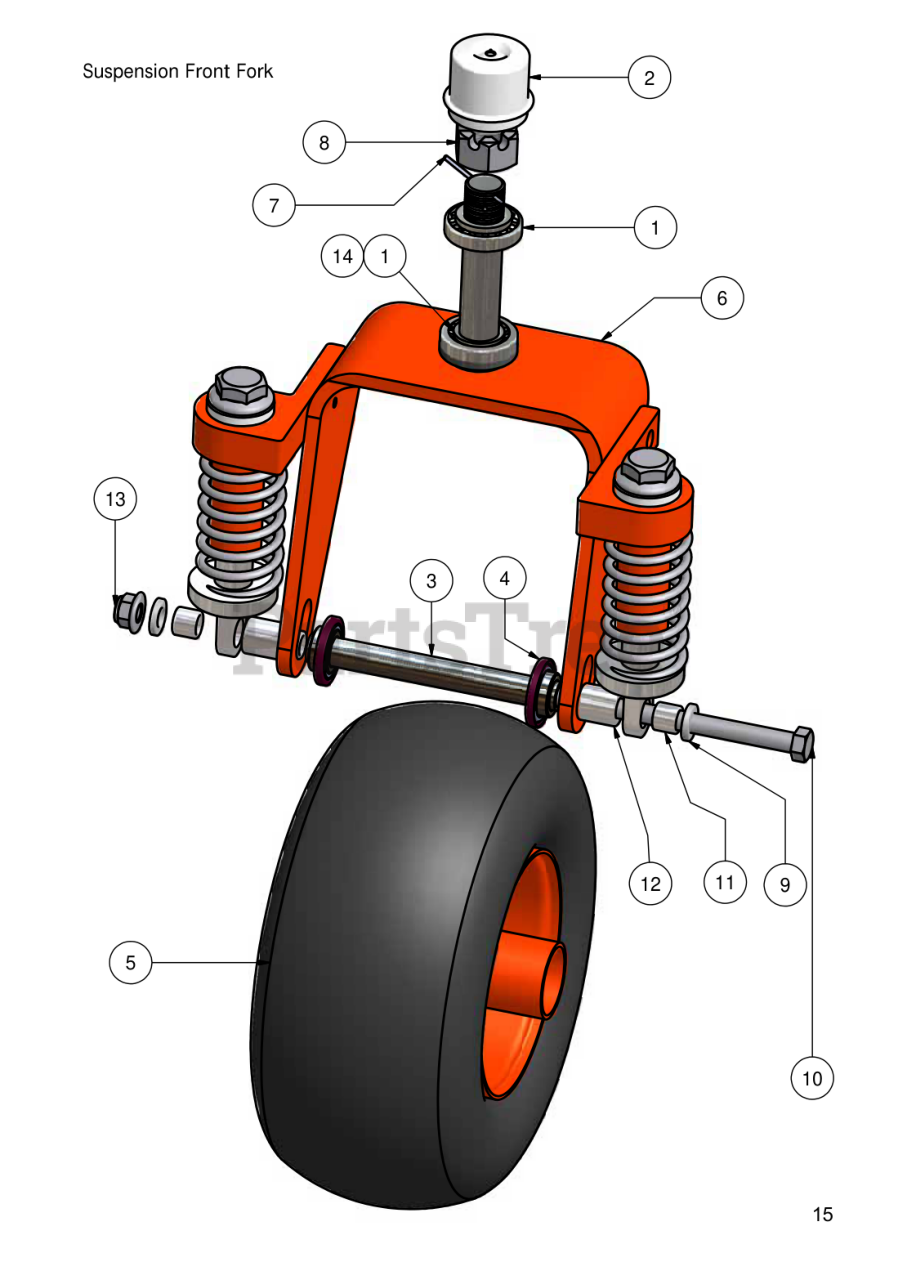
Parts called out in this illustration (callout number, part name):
2	Dust Cover
3	7" x 1/2" ID Tire Spacer
4	5/8" Bearing
5	13" x 6.50 -6 Tire and Orange Wheel
6	Suspension Front Fork
7	1/8" x 2 1/4" Cotter #8
8	1" Fine Threaded Castle Nut
9	1/2" Flat Washer for Suspension
10	1/2" x 13" Bolt
11	1/2" x 5/8" Spacer for Suspension
12	1/2" x 1 1/16" Spacer for Suspension
13	1/2" Flange Lock Nut
